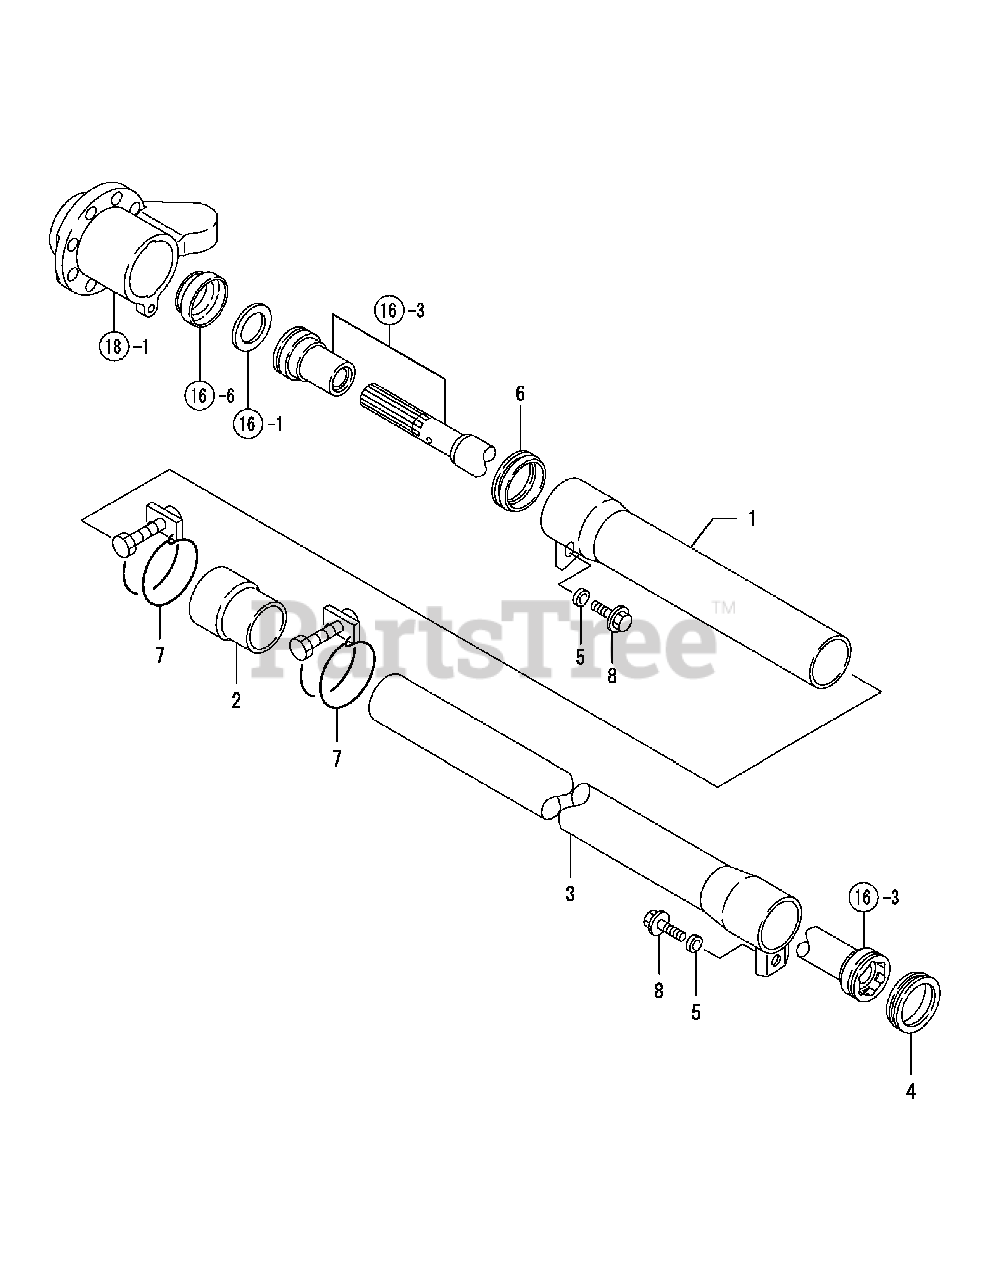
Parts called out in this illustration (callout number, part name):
1	COVER, FRONT SHAFT
4	SEAL 62 (SHAFT COVER)
5	COLLAR 8.1X10.5X4
6	SEAL 65 (SHAFT COVER)
8	BOLT M 8X 12 PLATED
